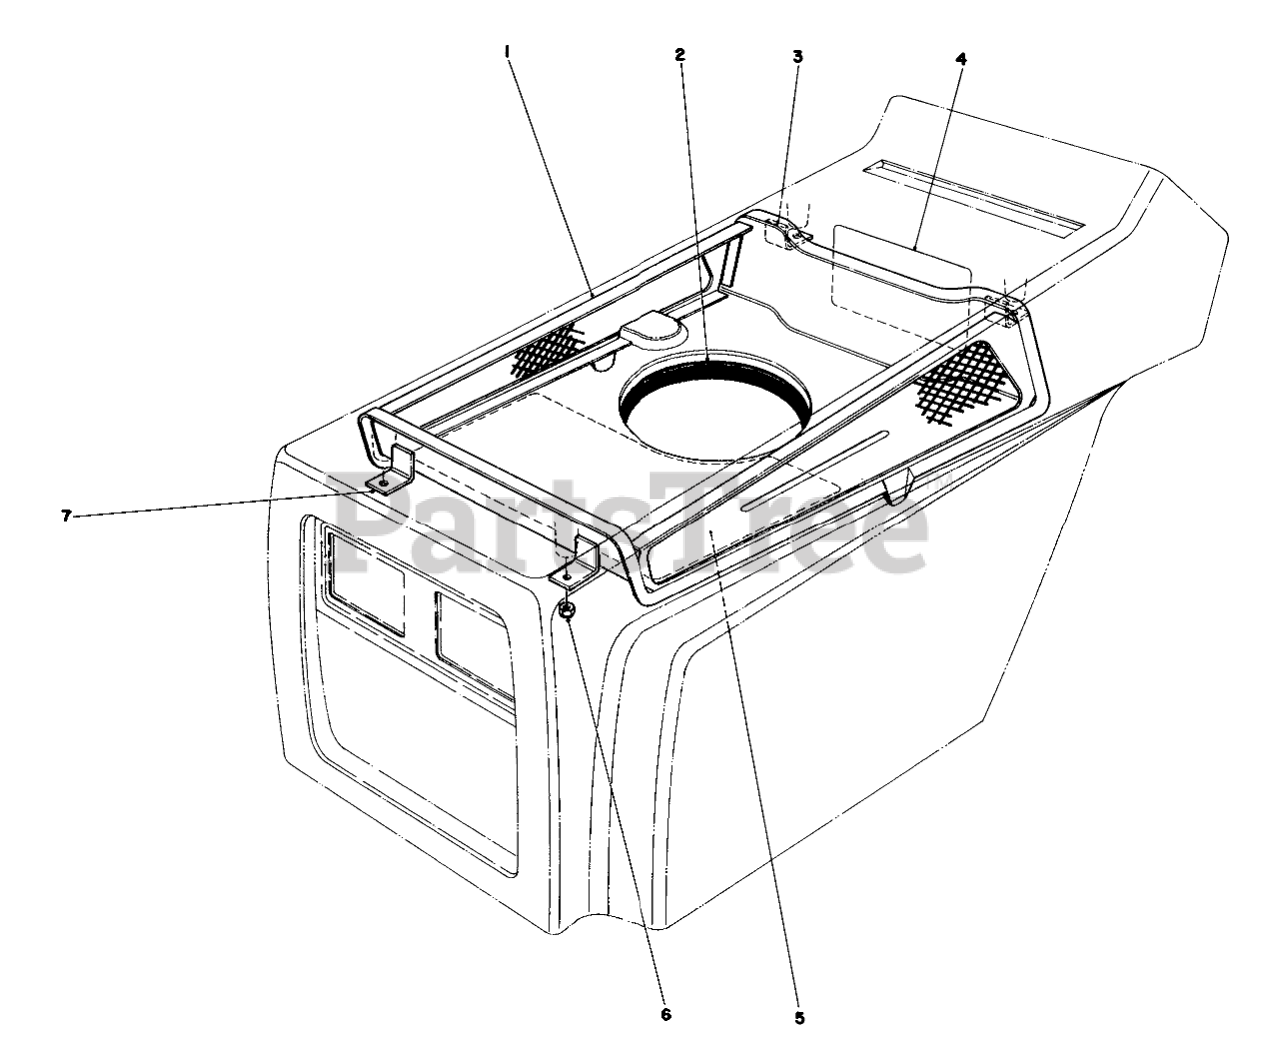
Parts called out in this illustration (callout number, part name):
1	Duct Hood
2	Seal Engine
3	Bracket Rear Duct Support
4	Decal-Belt Change
5	Decal Service
6	NUT-LOCK, CONE
7	Bracket Duct Support
